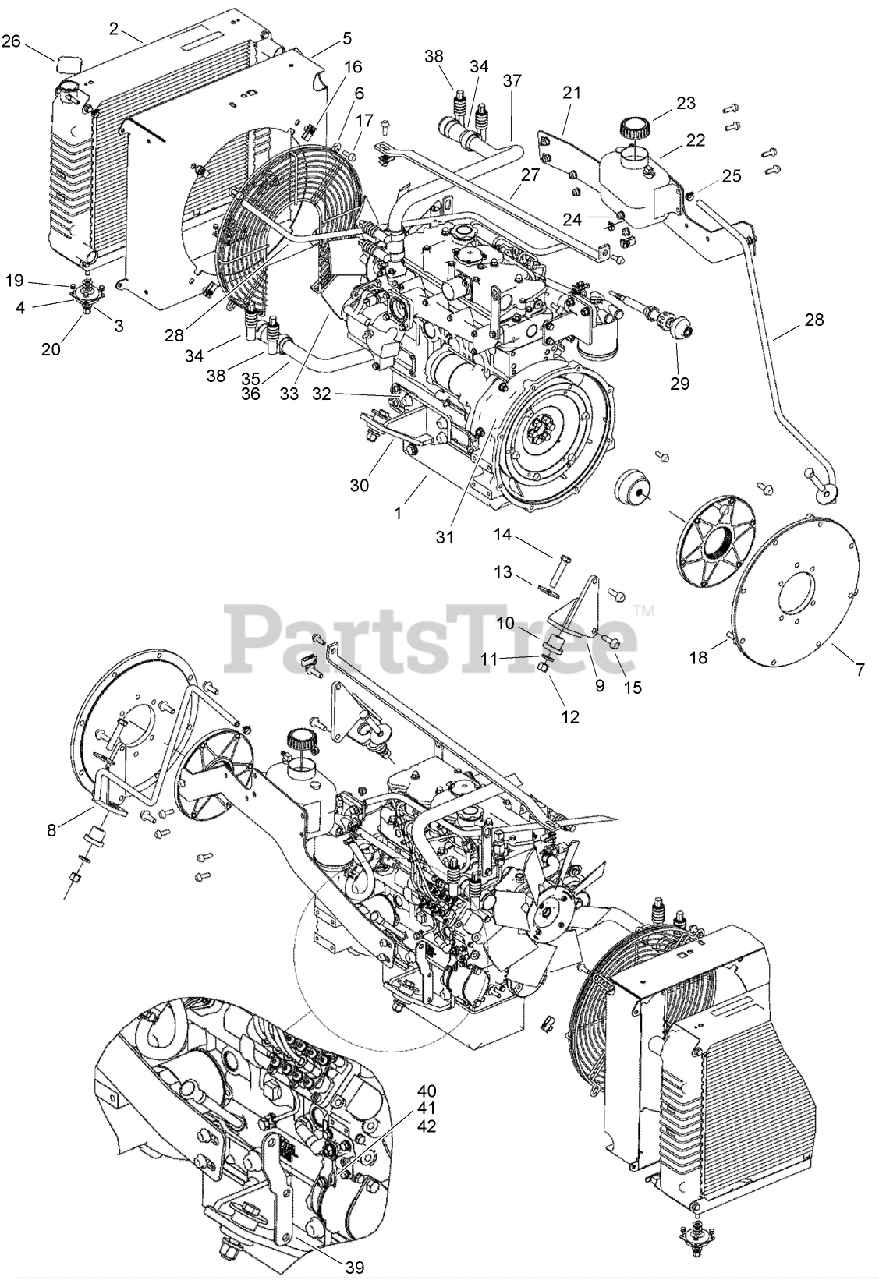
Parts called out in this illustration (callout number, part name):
1	ENGINE - CAT C1.6
2	RADIATOR
3	WASHER-FLAT
4	MOUNT-RADIATOR
5	SHROUD - Fan
6	GUARD-FINGER
7	PUMP DRIVE COUPLER KIT
8	WELDMENT - RR Motor Mount
9	WELDMENT - LR Motor Mount
10	MOUNT-RUBBER
12	NUT-HEX
13	WASHER-FLAT
14	SCREW-HH
15	SCREW-HHF
17	SCREW-HH
18	SCREW-HH
20	NUT-HEX
21	PLATE - Overflow Bottle Bracket
22	TANK-RECOVERY, COOLANT
23	CAP - Non-Vented w/Tether
24	NUT-TORQUE, PREVAILING
25	CLAMP-Hose
26	CAP-RADIATOR, 13 PSI
27	BAR - Radiator Support
28	HOSE - Coolant Recovery
29	CABLE-THROTTLE
30	WELDMENT - LF Motor Mount
31	WELDMENT - RF Motor Mount
32	SCREW, METRIC FLANGE w/BODY - M12 x 25
34	REDUCER - Straight, 1-3/8 - 1-1/8
35	TUBING - Radiator, Lower 1-1/8 OD x 16 Ga Wall
36	HOSE - Radiator, 28.58 ID x 76.2 Lg
37	TUBING - Radiator, Upper 1-1/8 OD x 16 Ga Wall
38	CLAMP-TORQUE, CONSTANT
39	Bracket-Throttle Cable
40	PIN-THROTTLE
41	SCREW - PHd Type 1 #10-32 x 1/2 CST ZND
42	PIN - Cotter .094 x 1.00 in Zn
